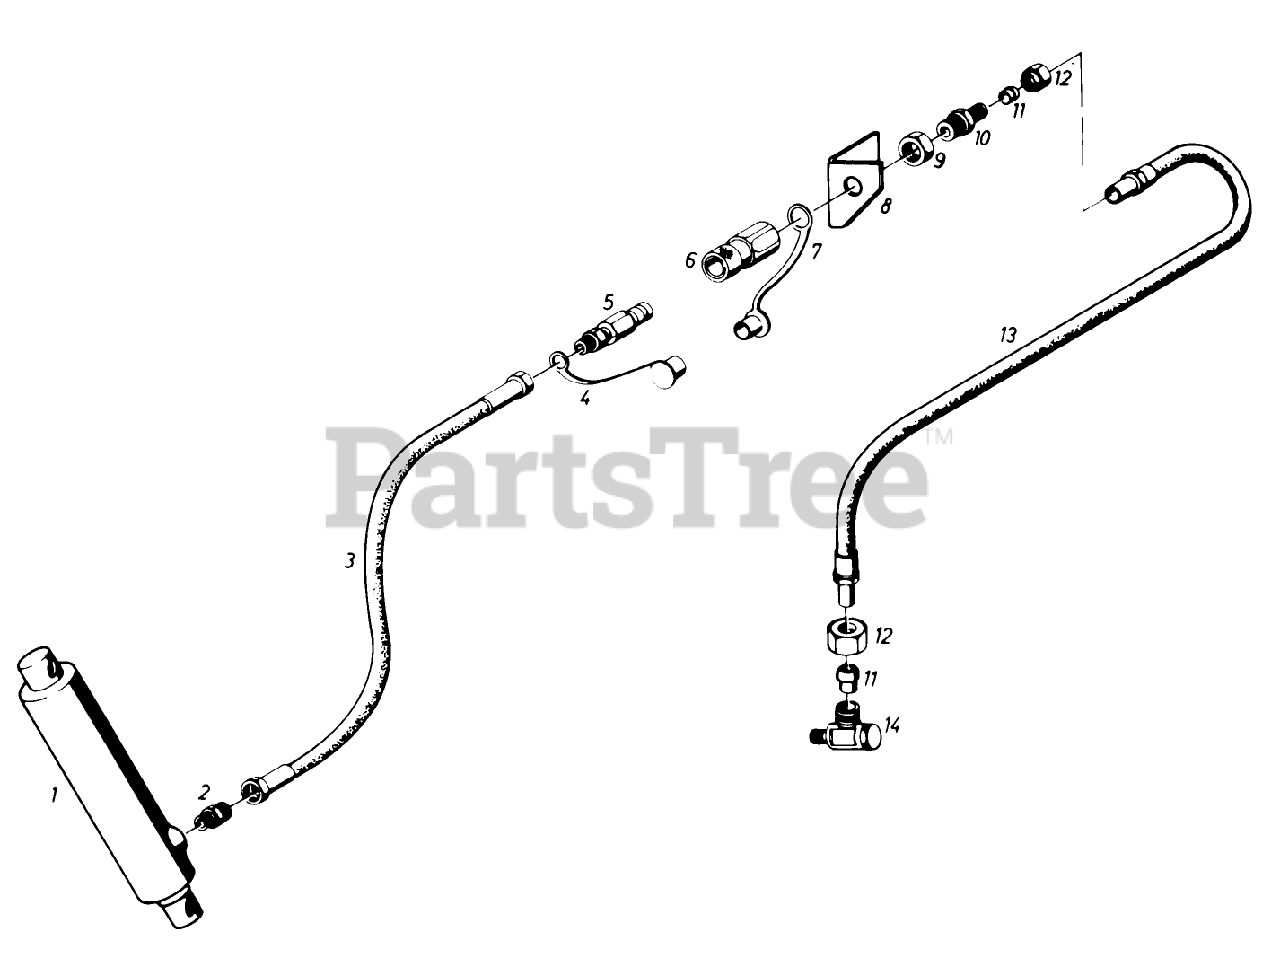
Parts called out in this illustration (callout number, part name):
1	Hydraulic Cylinder
2	FITTING
3	Hydraulic Hose
4	DUST CAP
5	Coupling Plug
6	Q.D. Fitting
7	Dust Cap
8	Mounting Plate
10	Fitting
11	RING SEAL
14	JOINT (CONSISTS 2 PT
